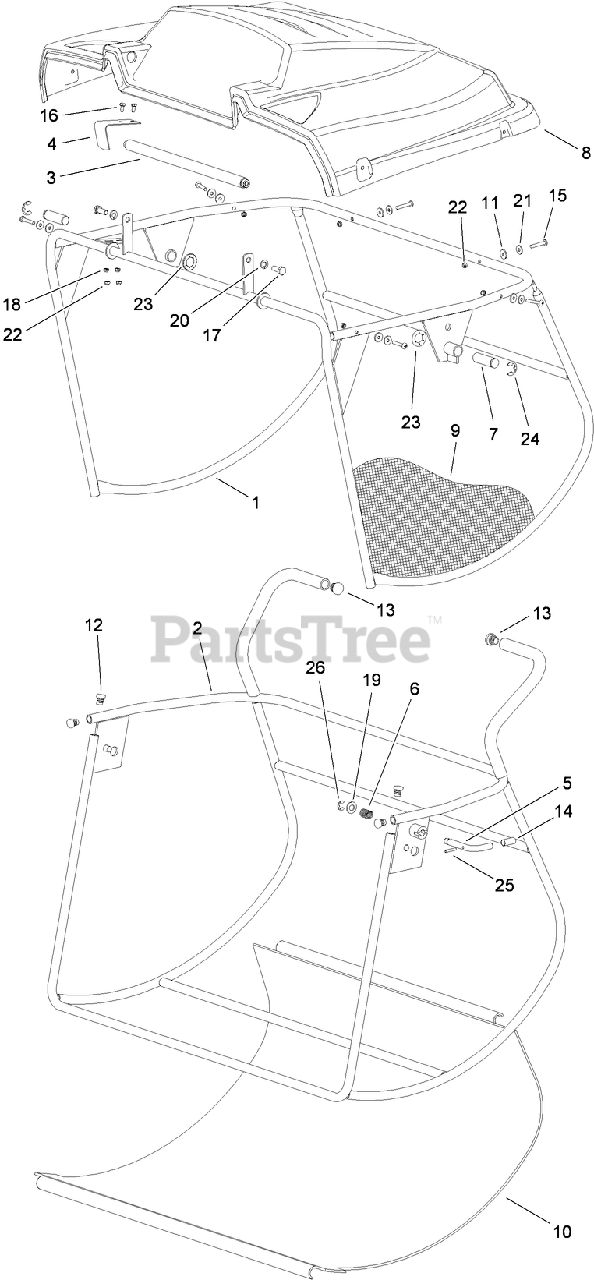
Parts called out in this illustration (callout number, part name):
1	UPPER FRAME ASM
2	LOWER FRAME ASM
3	HANDLE-LIFT
4	BRACKET-COLLECTOR, INTERLOCK
5	LEVER-COLLECTOR LOCK
6	SPRING
8	COVER-COLLECTOR
9	BAG-GRASS
10	BAG-LOWER
11	WASHER-RUBBER
17	SCREW-HH
18	WASHER
19	WASHER-FLAT
20	WASHER-SPRING
21	WASHER-FLAT
22	NUT-LOCK
23	RING-LOCK
24	E-CLIP
26	E-CLIP
